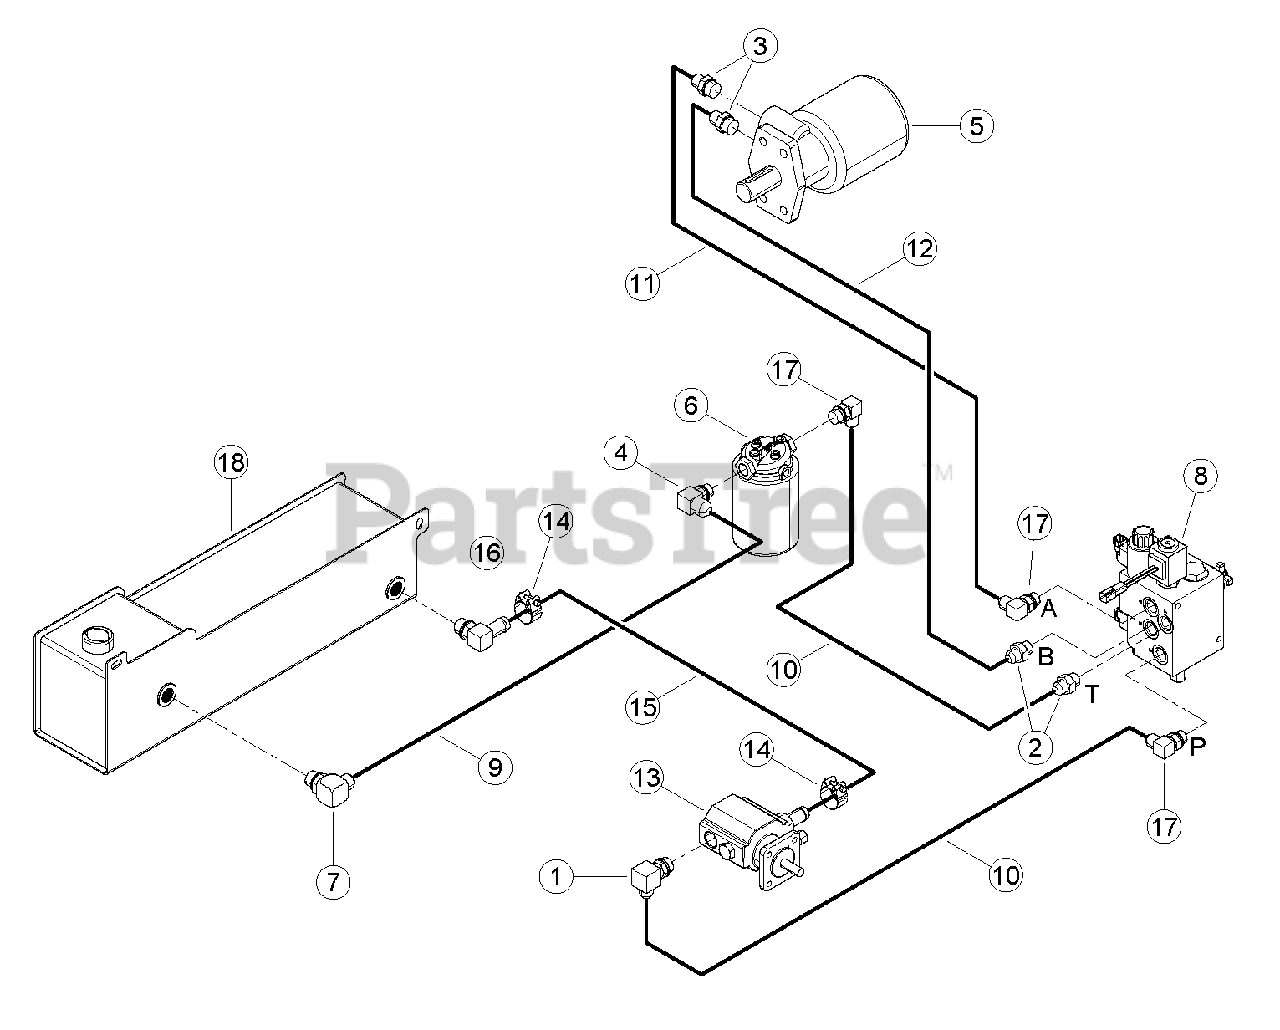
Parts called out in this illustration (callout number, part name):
1	ADAPTER, -10MORING/-8MJIC 90 DEG
2	ADAPTER, -8MORING/-8MJIC
3	ADAPTER, -10MORING/-8MJIC
4	ADAPTER, -8MORING/-10MJIC 90 DEG
5	MOTOR, 45 CU IN HYDRAULIC
6	FILTER, SPIN-ON
7	ADAPTER, -10MORING/-10MJIC 90 DEG
8	ASSEMBLY, CHIPPER VALVE (SEE VALVE ASSEMBLY FOR SERVICE PARTS. PAGE 8-9)
9	HOSE ASSY, -10FMJ/-10FMJ LD 90 X 21
10	HOSE ASSY, -8FMJIC/-8FMJIC90 X 21
11	HOSE ASSY, -8FMJIC/-8FMJIC90 X 61
12	HOSE ASSY, -8FMJIC/-8FMJIC X 61
13	PUMP, 2 STAGE CW HI/LO 0.605 DISP.
14	CLAMP, 1-5/32 TO 7/32 OD RANGE T-BOLT
15	HOSE, .75 ID X 24 IN. 100R4 HYD
16	ADAPTER, -10 MORING/.75 90 DEG HOSE
17	ADAPTER, -8MORING/-8MJIC 90 DEG
18	WELDMENT, HYDRAULIC TANK
